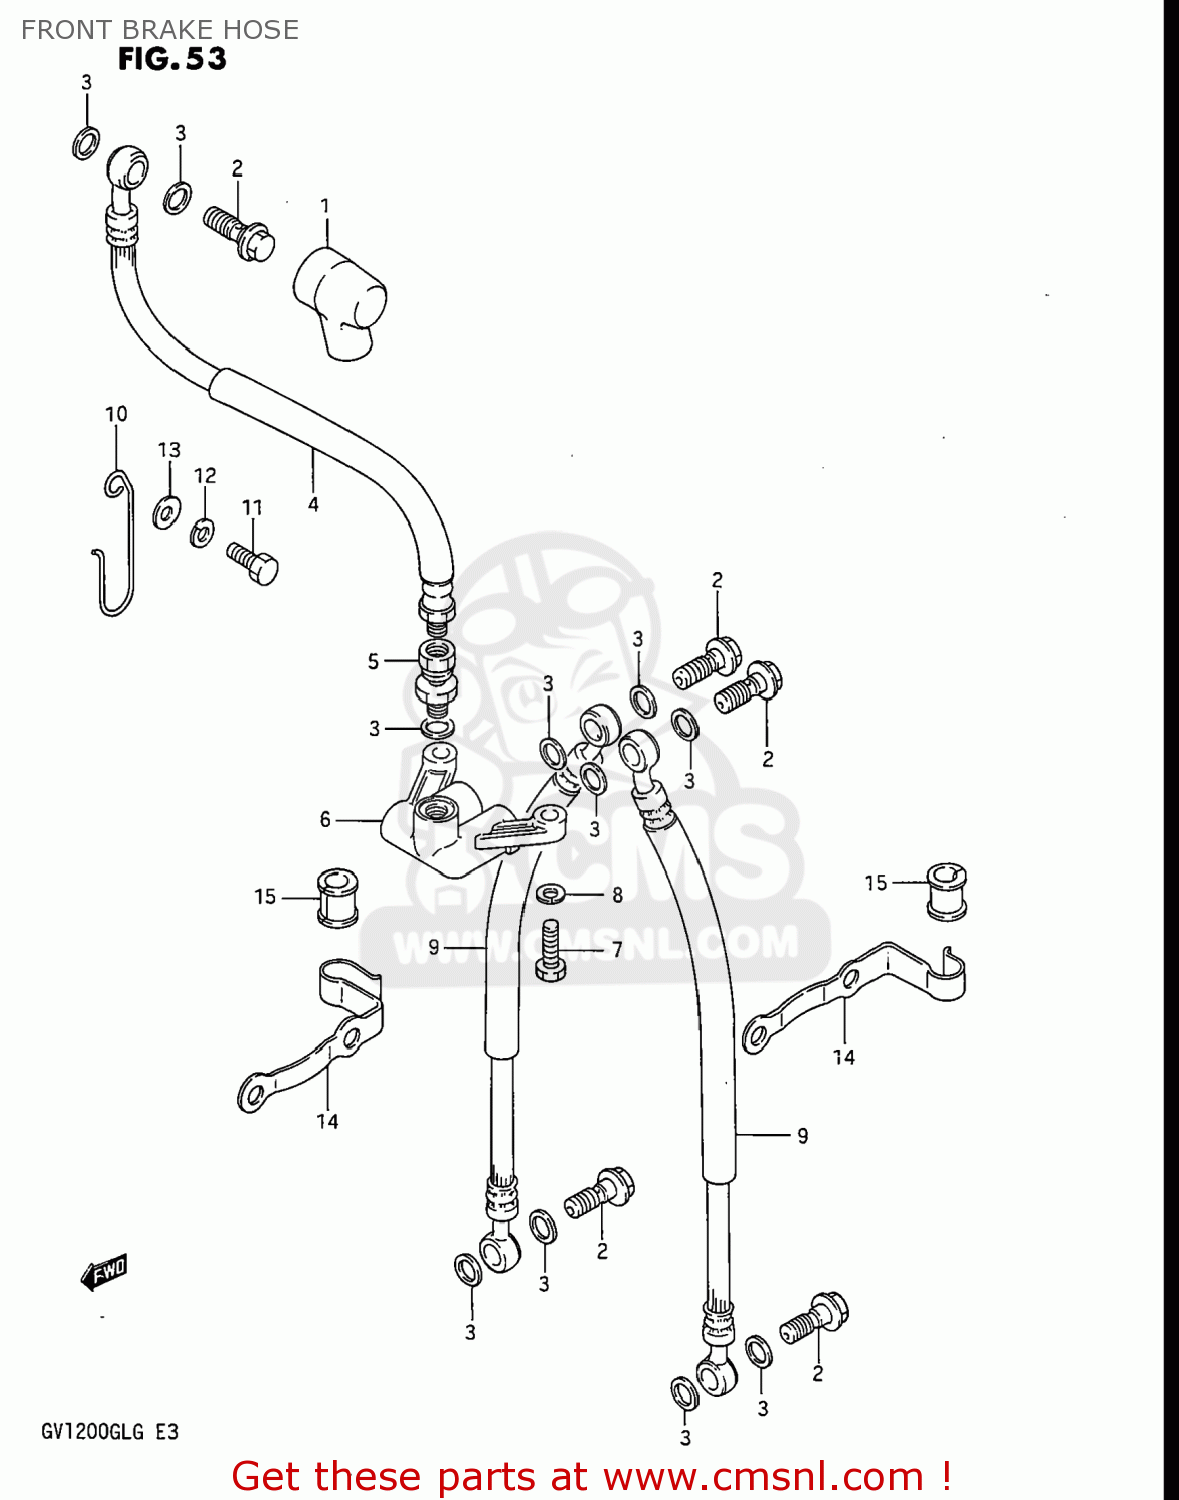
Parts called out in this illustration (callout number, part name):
1	BOOT,MASTER CYLINDER
2	BOLT UNION
3	WASHER(10X15X1.5)
4	HOSE,FRONT BRAKE NO.1
5	ADAPTER,BRAKE HOSE
6	JOINT,BRAKE HOSE
7	BOLT
8	WASHER,LOCK
9	HOSE,FRONT BRAKE NO.2
10	GUIDE,CLUTCH HOSE
11	BOLT
12	WASHER,LOCK
13	WASHER
14	GUIDE,BRAKE HOSE NO.2
15	BUSH,BRAKE HOSE GUIDE,NO.2
